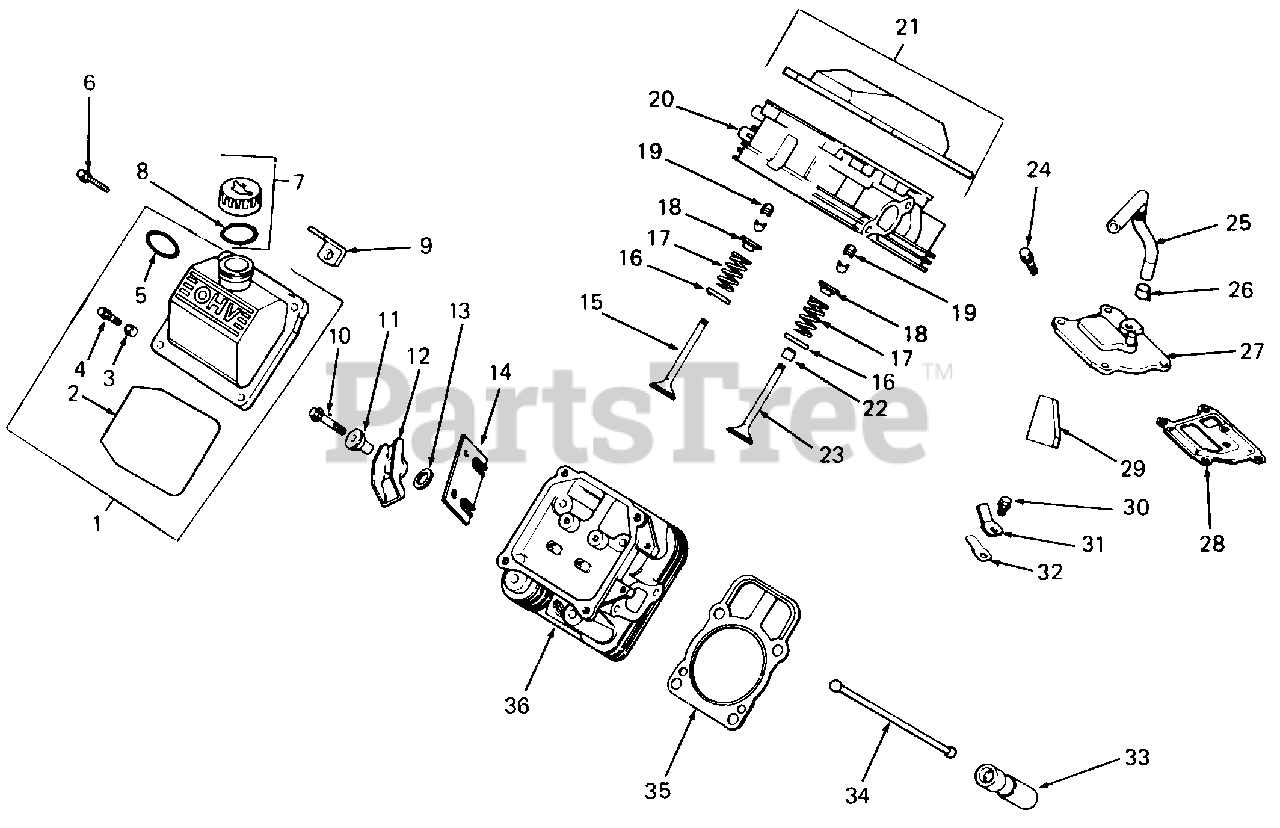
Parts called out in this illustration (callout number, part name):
1	Kit, Valve Cover w/Oil Fill
2	O-Ring, Cover
4	Screw, M6 X 1.0 X 30
5	O-Ring, Filler Neck
6	Screw, M10 X 1.5 X 91
7	Kit, Oil Fill Cap
8	O-Ring, Oil Fill Cap
9	Strap, Lifting
10	Screw, M6 X 1.0 X 34
11	Pivot, Rocker Arm
13	Washer, Flat
14	Plate, Guide
15	Valve, Exhaust, Std
16	Retainer, Spring
17	Spring, Valve
18	Cap, Valve Spring
19	Lock, Retainer
20	Head Assy, Cylinder #1
21	Kit, Valve Cover
22	Seal, Valve Stem
23	Valve, Intake, Std
24	Screw, M6 X 1.0 X 20
25	Hose, Breather
26	Clamp, Hose
27	Cover, Breather
28	Gasket, Breather
29	Filter, Breather
30	Screw, Breather Reed Retainer, M5 X 0.8 X 10
31	Retainer, Breather Reed
32	Reed, Breather
33	Lifter, Valve
34	Rod, Push
35	Gasket, Cylinder Head
36	Head Assy, Cylinder #2
